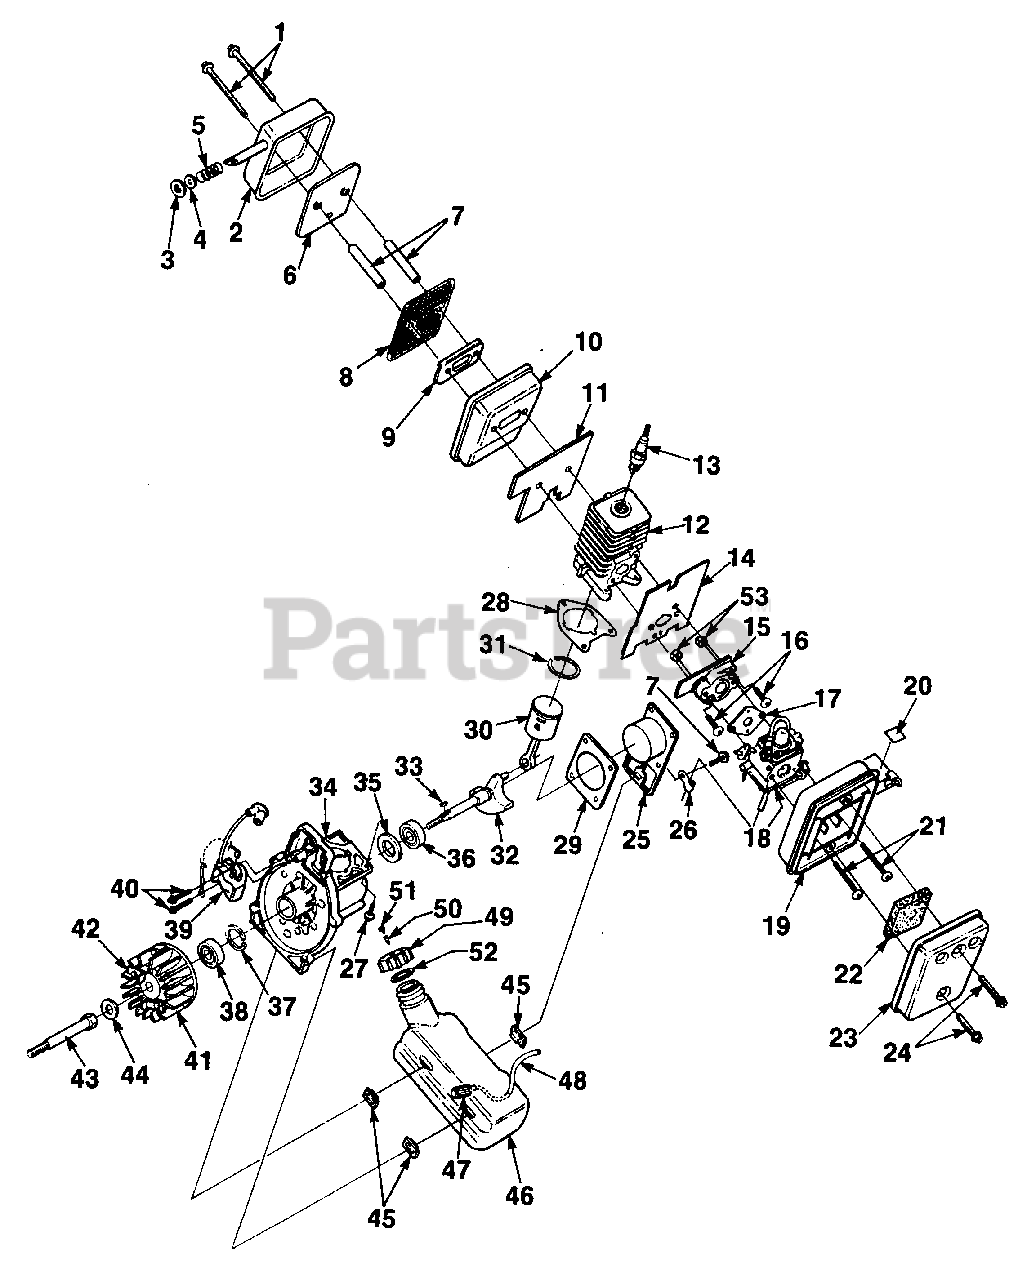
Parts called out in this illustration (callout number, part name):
1	SCREW - Sems Hex Hd. (10-24 x 2 1/2)
2	COVER - Muffler
3	WASHER - Insulating
4	WASHER - Flat
5	SPRING - Compression
6	DEFLECTOR - Muffler
7	SPACER - Muffler
8	SCREEN - Spark arrestor
9	PLATE - Reinforcing
10	BODY - Muffler
11	GASKET - Muffler
12	CYLINDER
13	SPARK PLUG
14	GASKET - Heat dam
15	HEAT DAM
16	SCREW (T-25 Torx)
17	GASKET - Carburetor
18	CARBURETOR (WT-80) Walbro
19	BOX - Air filter
20	DECAL - Choke/Run
21	SCREW - Thread Forming
22	AIR FILTER
23	COVER - Air filter
24	SCREW - Thread forming 8-16 x 3/4
25	COVER - Crankcase
27	SCREW - Thd forming #10-24 x 3/4
28	GASKET - Cylinder
29	GASKET - Crankcase
30	PISTON & ROD ASSEMBLY
31	RING - Piston
32	CRANKSHAFT
33	KEY - Woodruff
34	CRANKCASE ASSEMBLY
35	SEAL - Shaft
36	BEARING - Ball
37	RING - Retaining
38	BEARING - Ball
39	MODULE - Ignition
40	SCREW - Thd forming 8-32 x 1
41	ROTOR & STARTER PAWL
42	STARTER PAWL KIT
43	ADAPTER - Fan
44	WASHER - Flat 5/16
45	BUMPER - Rubber
46	TANK - Fuel
47	FILTER - Fuel
48	TUBING - Rubber
49	FUEL CAP ASSEMBLY
50	VALVE - Duck Bill
51	FILTER
52	GASKET - Fuel cap
